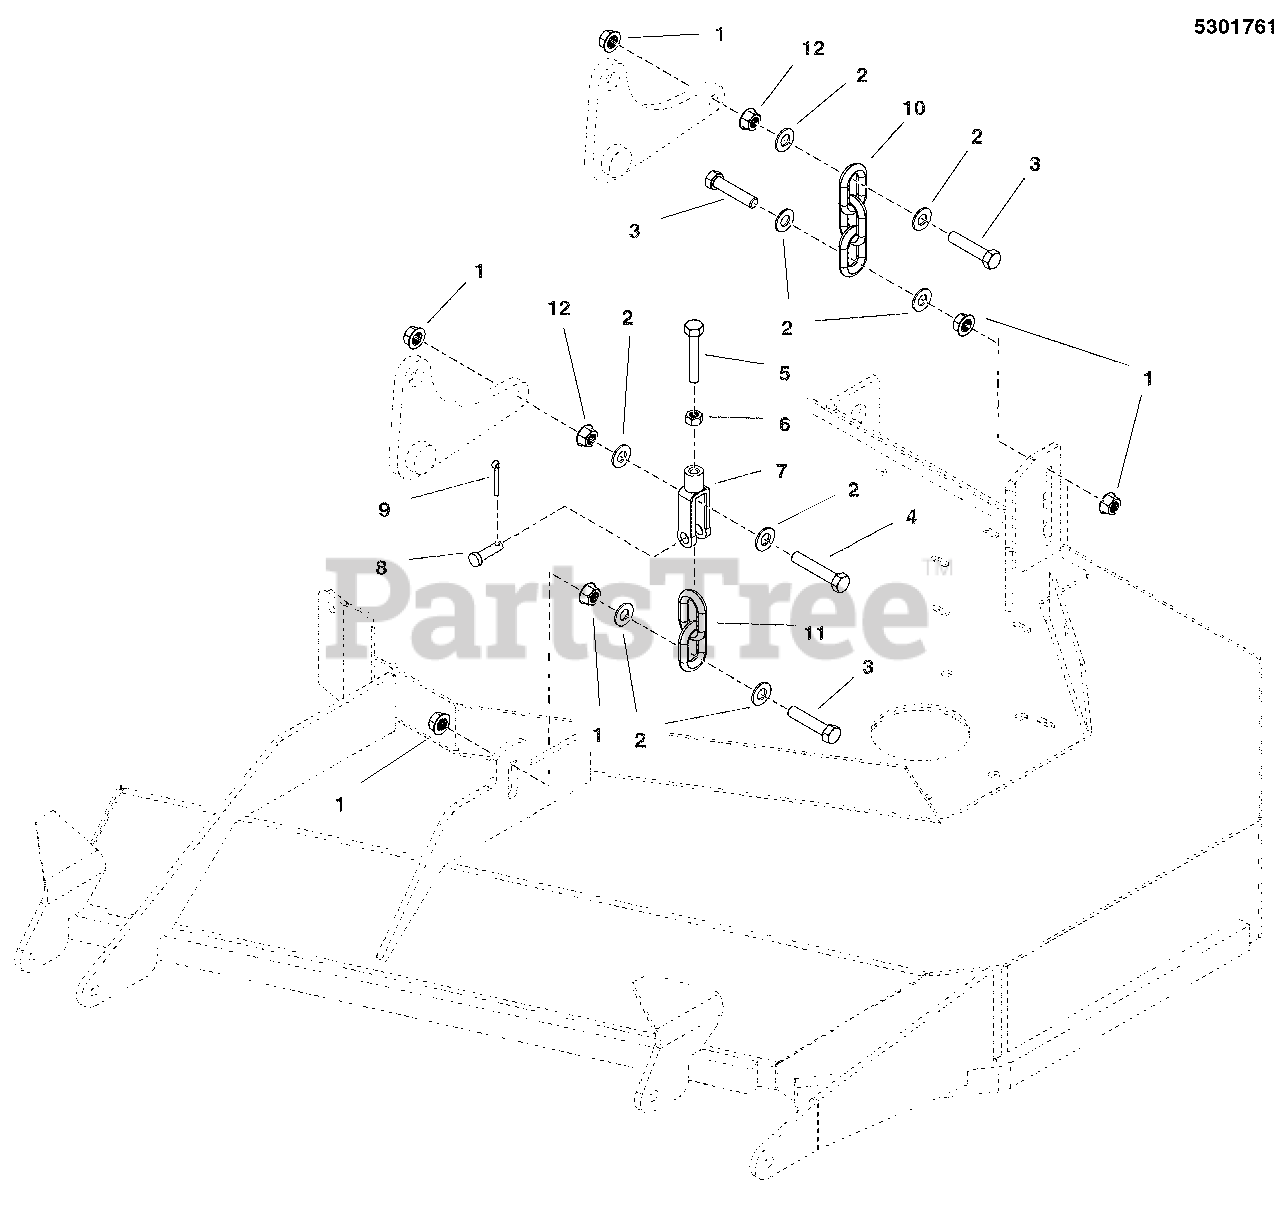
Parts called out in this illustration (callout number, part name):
1	NUT, 3/8-16 HEX SERRATED FLANGE
2	WASHER, 3/8 SAE
3	BOLT, 3/8-16 X 1-3/4" GD5 CZ
4	BOLT, 3/8-16 X 2, GD5, CZ
5	BOLT, 5/16-18 X 2 GD5 TFL
6	NUT, 5/16-18 HEX
7	CLEVIS, 5/16-18, 3/8 PIN HOLE
8	PIN, CLEVIS, 3/8 X 1-1/8
9	PIN, 3/32 X .750, COT, ZINC/CLEAR
10	CHAIN, 5/16 GD30, 3 LINKS
11	CHAIN, 5/16 GD30, 2 LINKS
12	NUT, 3/8-16 HEX JAM
